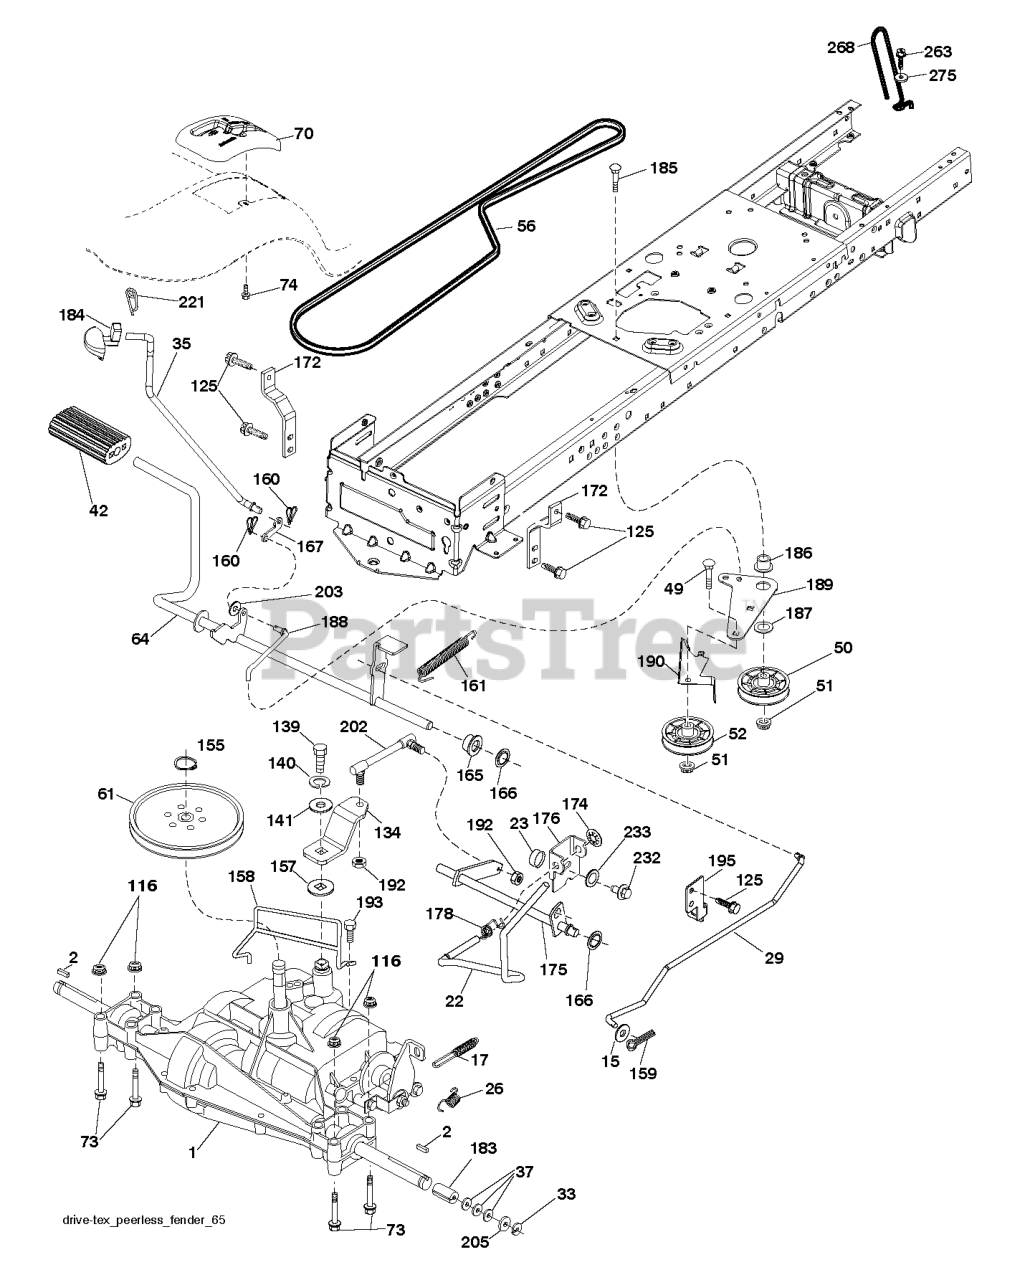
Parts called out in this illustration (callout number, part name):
2	SQUARE KEY
15	WASHER
17	SPRING.BRAKE.PEERLESS.TEX
22	ROD.SHIFT.FENDER.TLT.2006
23	KNOB.DUCKHEAD.1/2
26	SPRING.BRAKE.RTN.GR.DR
29	ROD.BRAKE.PEERLESS
35	ROD.CNTRL.PARK.PREDATOR.LT.TEX
42	PEDAL COVER T
50	IDLER.FLAT.910.OFFSET
51	NUT LOCK FLG 3/8-16 UNC
52	IDLER.V-GROOVE.910.OFFSET
56	V-BELT.TRACTOR.DRIVE.P
61	PULLEY TRANS
64	SHAFT.ASM.PEDAL.BRAKE.
70	CONSOLE ASM.STL.6SP.ROS.TEX.GR
73	BOLT
74	SCREW.HI-LO.CONSOLE
116	NUT LOCK HEX FLANGE 5/16-18
125	SCREW
139	BOLT 1/4-28X3/4
140	LOCKWASHER
141	WASHER LT
155	RETAINING RING LT
157	WASH-SHFT PLT LT
158	KEEPER.PMS.18/20.D4365
159	COTTER PIN
160	RETAINER CLIP
161	SPRING, RETURN LT
165	BUSHING.SHAFT.BRAKE.HAND
166	NUT.PUSH.625
167	LATCH.BRAKE.SPRING
172	STRAP.TRQ.LH.GEAR.DRIV
174	NUT.PUSH.500.2006
175	SHAFT ASM SHIFT
176	ARM.CLEVIS.ROD.SHIFT
178	SPRING.SHIFT.GT2006
183	SPACER AXLE
184	HANDLE.PARKNG BRK.PRED.LT.428
186	SPACER.RETAINER
187	WASHER 12/32X2X10GA
188	RP.LINK.CLUTCH.GROUND.DRIVE
189	BELLCRANK.GROUND.DRIVE.TEX.
190	KEEPER.BELLCRANK.DRIVE
192	NUT LOCK CENTER 1/4 -28 FNTHD
193	SCREW 5/16"
195	BRKT.ROD.BRAKE.PEERLES
202	LINK.SHIFT.PMST.18" (SPG1286)
203	WASHER
221	RETAINER.SPRING.CLIP.H
232	BOLT FIN HEX 7/16-14 X 1
233	WASHER SERRATED
263	SCREW, 3/8-16X3/4
268	GUARD MUFFLER
275	WASHER
